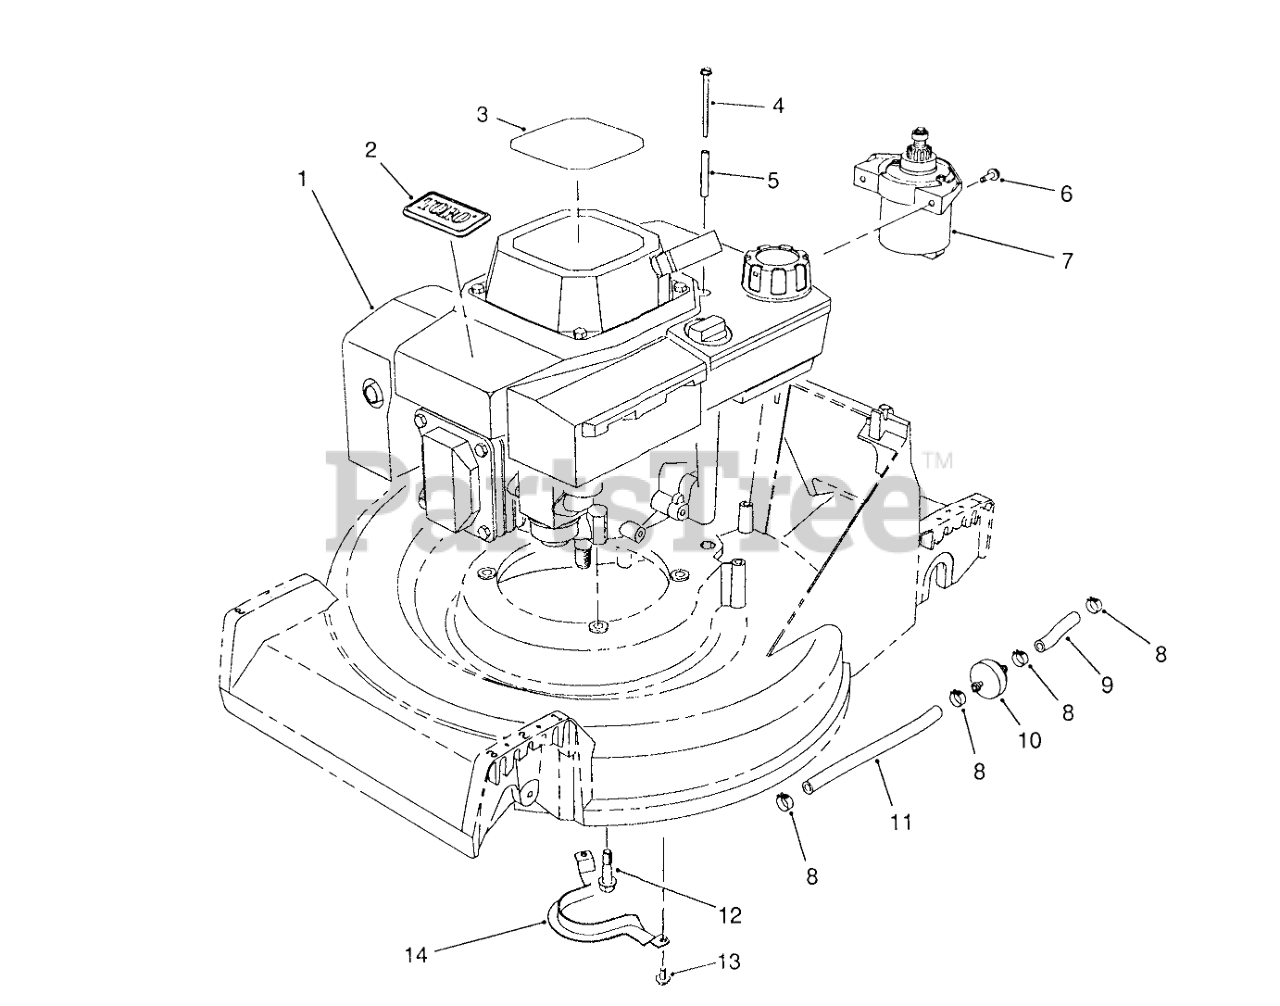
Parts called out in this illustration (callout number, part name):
1	ENGINE ASSY OHV BBC/K
2	TORO LOGO PLT
3	DECAL-HV INT'L
4	THRD FORMING SCREW
5	TUBULAR SPACER
6	SCREW
7	STARTER MOTOR ASM
8	CLAMP-FUEL LINE
9	LINE-GAS
10	FILTER-FUEL
11	HOSE-FUEL
12	SCREW-HWHTF
13	SCREW-HWHTF
14	Guide-Belt
